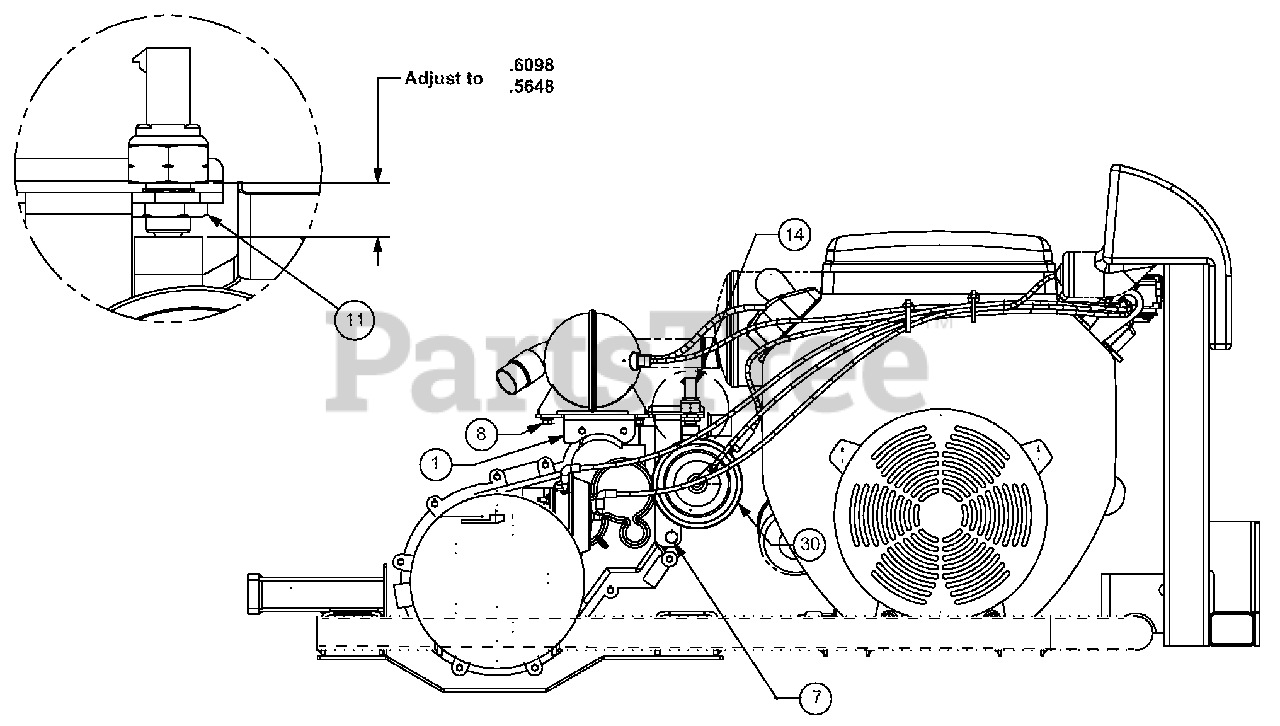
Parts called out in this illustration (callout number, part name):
1	Mounting Bracket, Vacuum Actuator
7	Screw, 5/16-18
8	Screw, 1/4-14
11	Nut, Hex 9/16-18
14	Switch, Neutral
30	Actuator, Vacuum Shift
